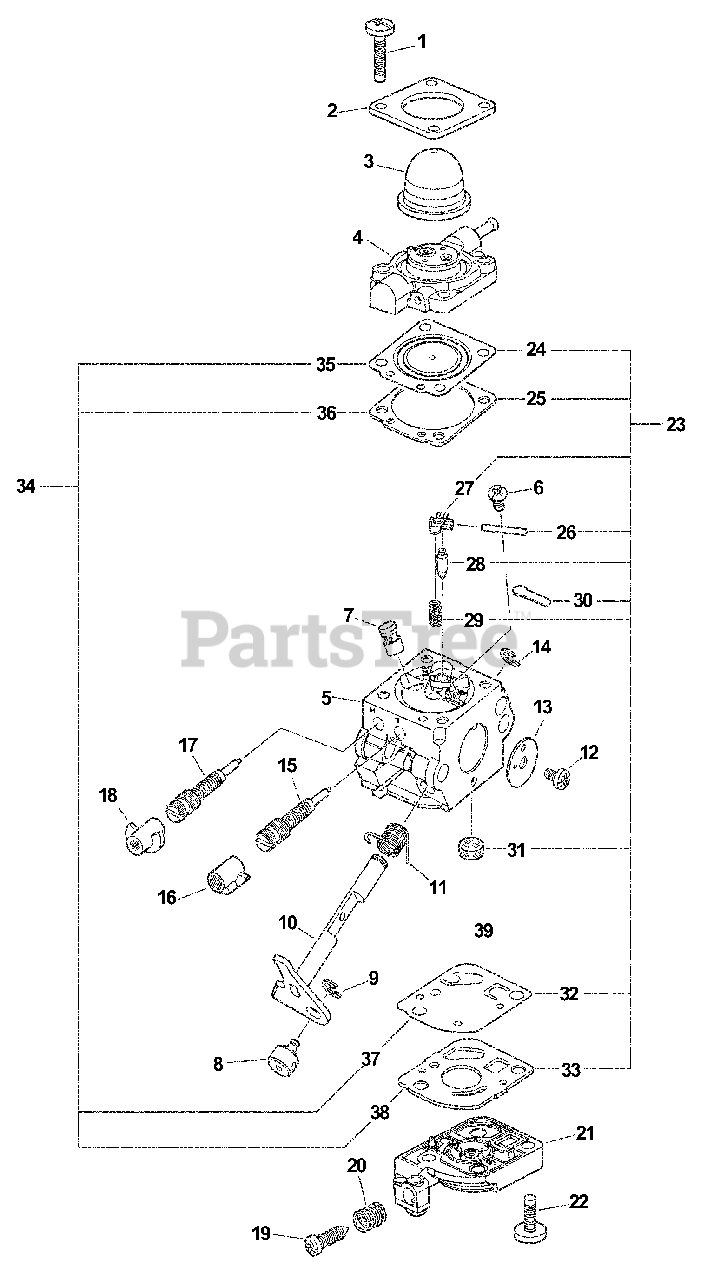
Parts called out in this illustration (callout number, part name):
1	SCREW, RETAINER
2	RETAINER, PURGE BULB
3	BULB, PURGE
4	BASE, PURGE
5	BODY, CARBURETOR
6	SCREW, METERING LEVER PIN
7	NOZZLE, CHECK VALVE
9	RING, RETAINING
10	SHAFT, THROTTLE
11	SPRING, RETURN
13	VALVE, THROTTLE
14	RING, RETAINING
15	NEEDLE - LOW SPEED
16	CAP, LIMITER
17	NEEDLE - HIGH SPEED
18	CAP, LIMITER
19	SCREW, IDLE ADJUST
20	SPRING, IDLE ADJUST
21	BASE, PURGE
22	SCREW, PUMP COVER
23	REPAIR KIT
24	DIAPHRAGM, METERING
25	GASKET, METERING
26	PIN, METERING LEVER
27	LEVER, METERING
28	VALVE, INLET NEEDLE
29	SPRING, METERING LEVER
30	PLUG, WELCH
31	STRAINER
32	DIAPHRAGM, PUMP
33	GASKET, PUMP
34	DIAPHRAGM/GASKET KIT
35	DIAPHRAGM, METERING
36	GASKET, METERING
37	DIAPHRAGM, PUMP
38	GASKET, PUMP
